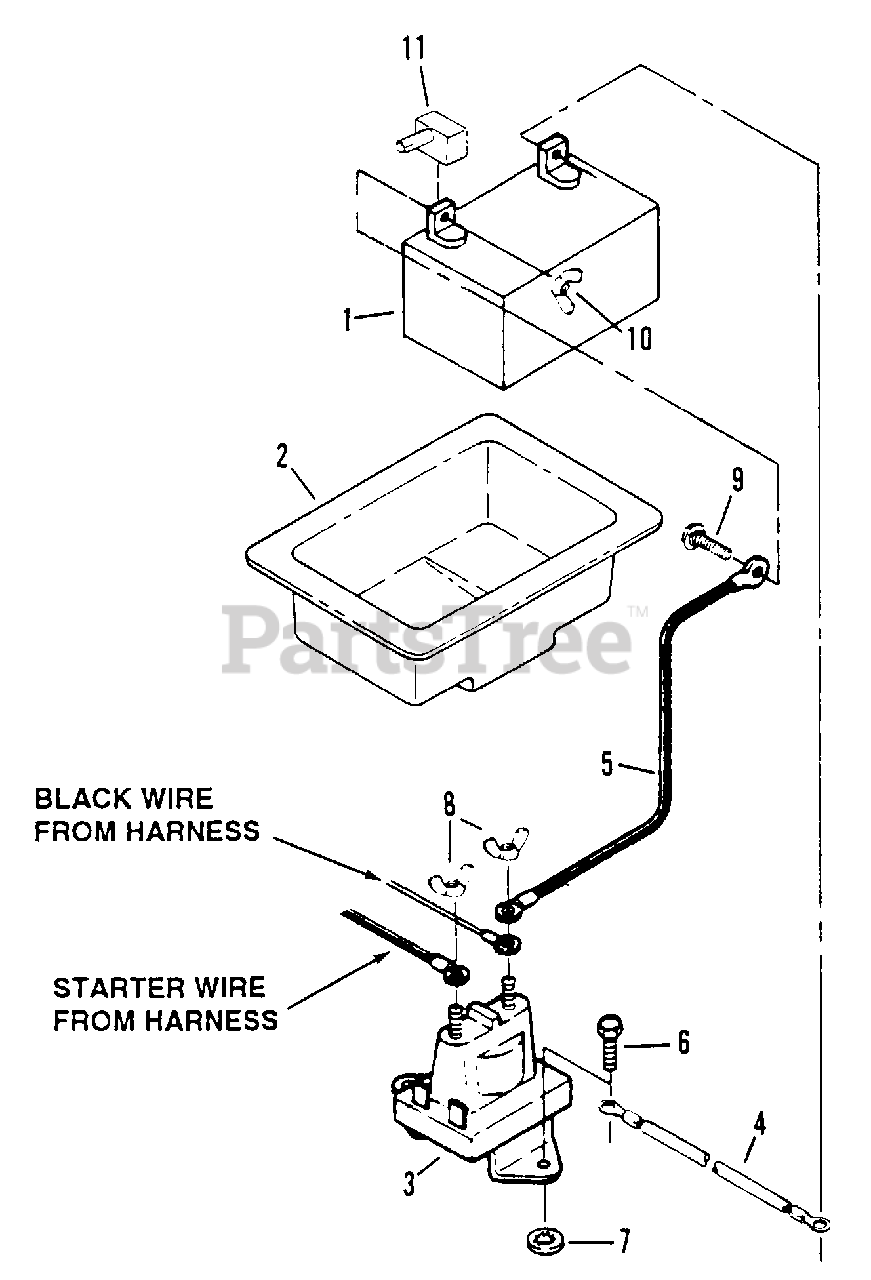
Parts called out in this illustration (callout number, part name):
1	KIT, Battery
2	TRAY, Battery
3	SOLENOID
4	CABLE, Ground (Black)
5	CABLE, Positive (Red)
6	SCREW, 1/4-20 x 1/2" Self-Tapping
7	RETAINER, 1/4 Bolt
8	NUT, 1/4-20 Locking Wing
9	BOLT, 1/4-20 x 3/4" Carriage
10	NUT, 1/4-20 Wing
11	COVER, Positive Terminal
